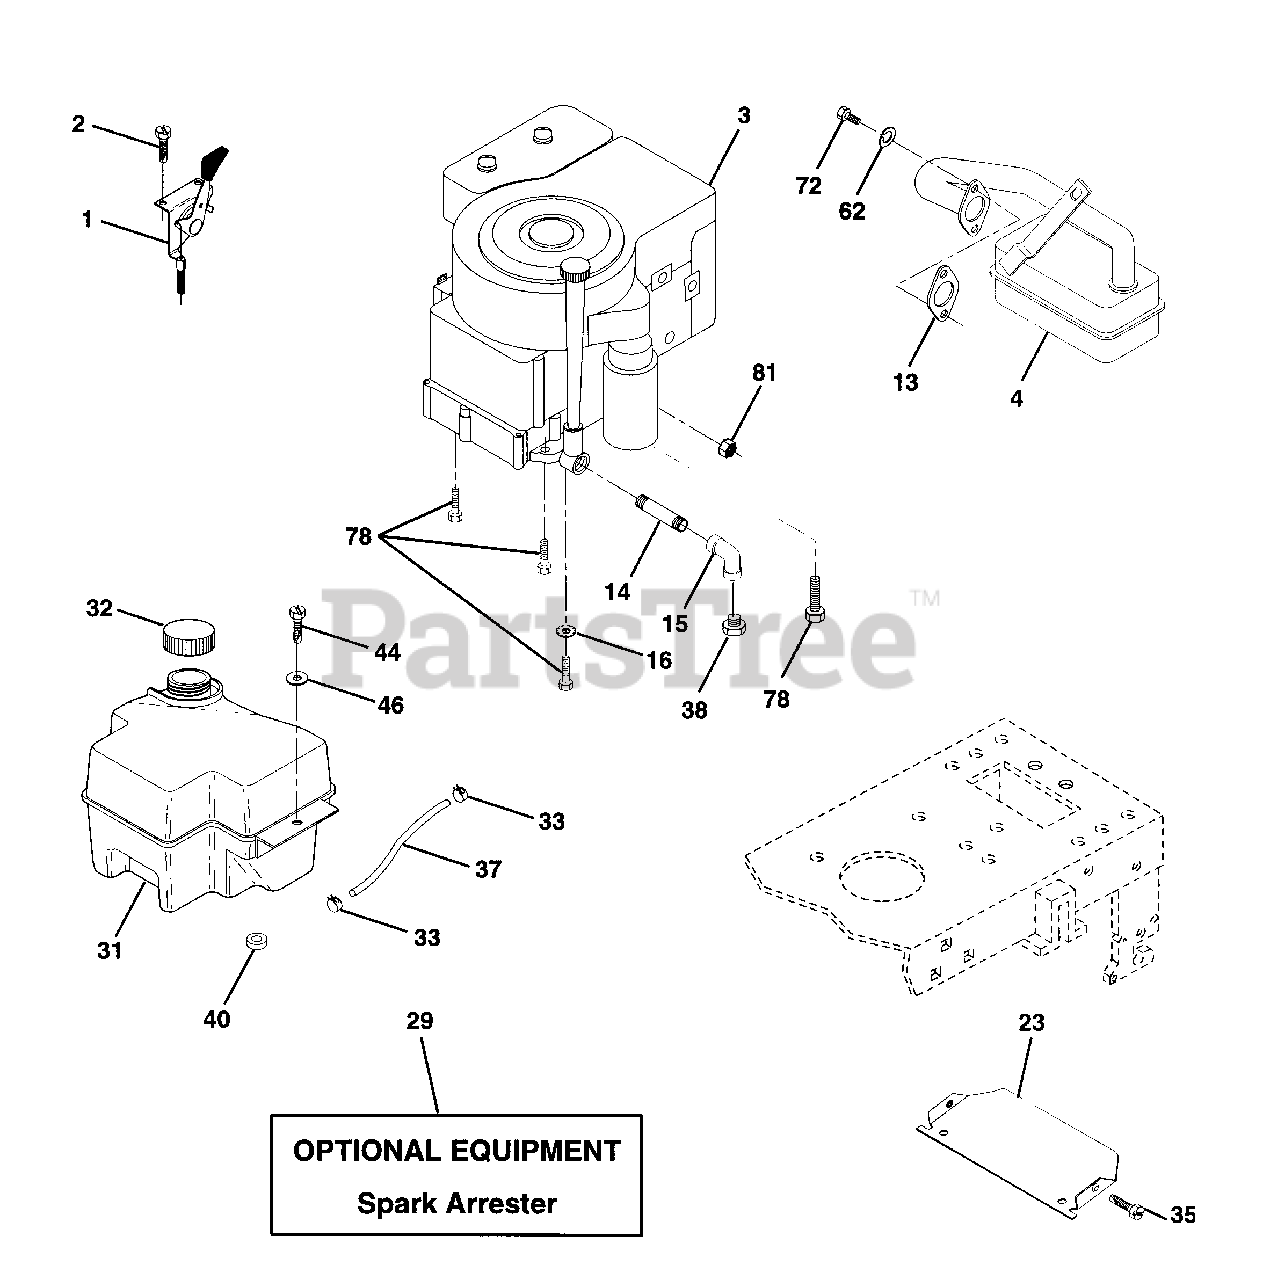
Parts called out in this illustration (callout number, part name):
1	Control Th/ch 23 5 LH Flag
2	Screw Hex Thd Cut 1/4-20x5/8 T
4	Muffler LT B&S 14.5
13	Gasket Eng 1 313 Id Tin Plated
14	Nipple Pipe 3/8 Npt X 3"
15	Elbow Std 90 Degree 3/8-18 Npt
16	Washer Lock Ext Tooth 3/8
23	Shield Heat
29	Kit Spark Arrestor (Flat Scrn)
31	Tank Fuel Front 2 00
32	Cap Asm Fuel W/sym Vented
33	Clamp Hose Black
35	Screw
37	Line Fuel 20"
38	Plug Oil Drain (Order From Engine Manufacturer)
40	Bushing Snap Nyl Blk Fuel Line
44	Screw Hexwsh Thdrol 1/4-20x3/4
46	Washer 9/32 X 7/8 X 16 Ga
62	Washer Lock Hvy Hlcl Spr 5/16
72	Screw Hexhd Cap 5/16-18x 3/4
78	Screw Thdrol 3/8-16x1-1/4 TYTT
81	Nut Flange 1/4-20 Starter Nut
